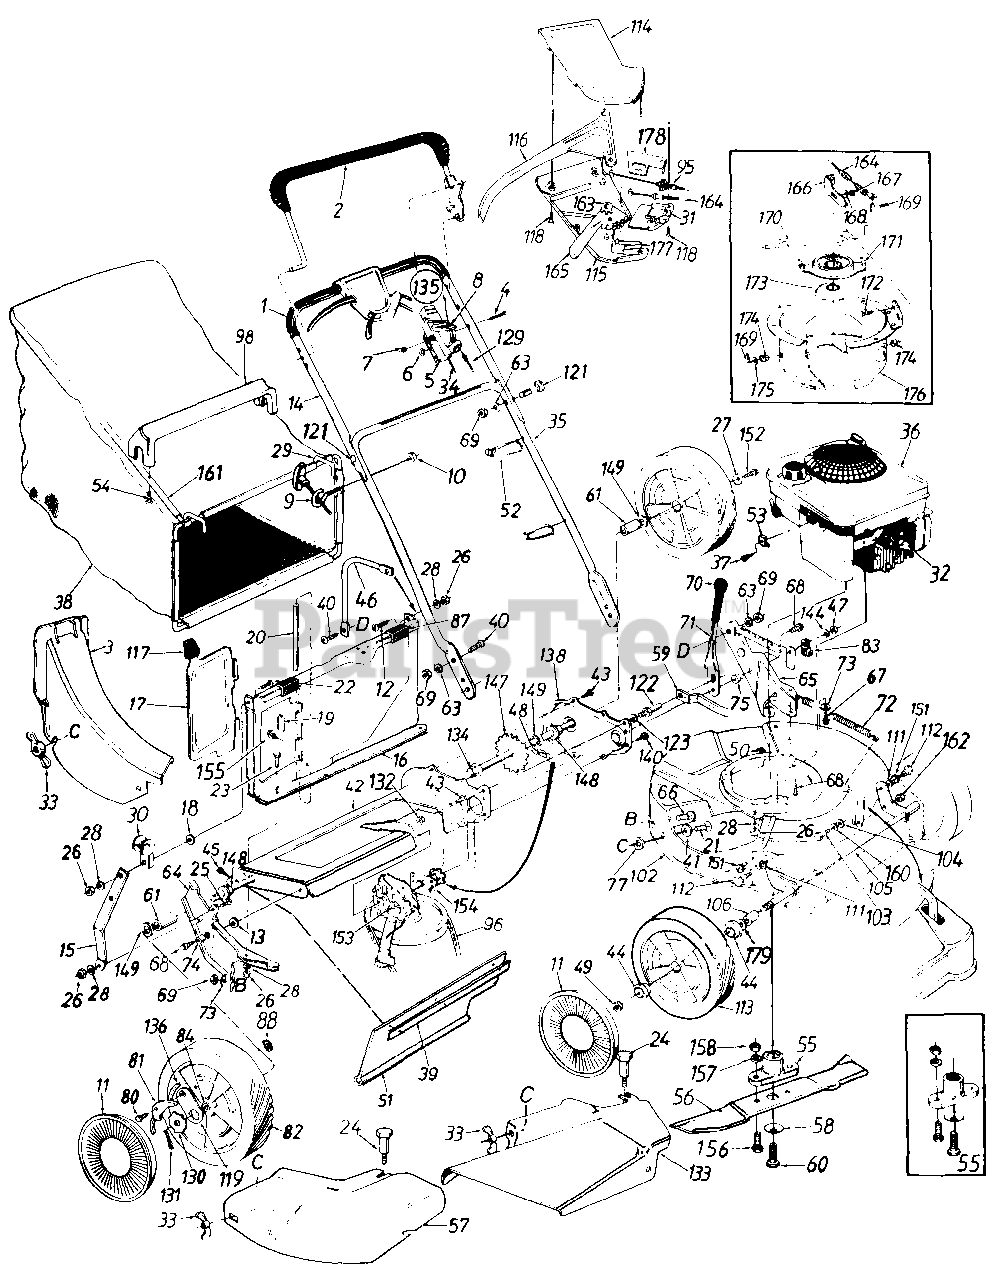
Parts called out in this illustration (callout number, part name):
1	Foam Grip
2	Control Handle Ass'y.
3	Rear Discharge Chute Ass'y.
4	Oval C-Sunk Scr.
5	Throttle Body
6	Spr. Wash. .66" I.D.
7	Hex L-Nut 1/4-20 Thd.
8	Throttle Lever
9	Rope Guide Bolt
10	Hex L-Nut 1/4-20 Thd.
11	Hub Cap
12	Truss Mach. Scr. 1/4-20 x .62" Lg.
13	Fl-Wash. .383" I.D. x 1" O.D.
19	Torsion Spring
21	Carriage Bolt 1/4-20 x .62"
22	Truss Mach. Scr. 1/4-20 x 3/4" Lg.
23	Hex Bolt 1/4-20 x .50" Lg.
24	Shoulder Bolt .312 Dia. x .18 Lg. - Special
25	Hex Bolt 1/4-20 x .62" Lg.
26	Hex Nut 1/4-20 Thd.
27	Bell-Wash. 1/4" I.D.
28	L-Wash. 1/4" I.D.
31	S.P. Control Cover
32	Spark Plug Insulator
33	Wing Nut w/Washer
34	Throttle Control Wire 61"
35	Lower Handle - Painted
36	Engine
37	Hex Self-Tap Scr. #10-32 x .62" Lg.
38	Grass Bag
39	Retaining Strip
40	Truss Mach. Scr. 5/16-18 x .75" Lg.
41	Fl-Wash. .344" I.D. x .62"
44	Flange Ball Bearing 1/2" I.D.
45	Hex AB-Tap Scr. 1/4 x .62"
46	Catcher Panel Support Arm
47	Hex Patch L-Nut 3/8-24 Thd.
48	#48 Chain .500" Pitch x 30 Links
49	Hex L-Nut 3/8-16 Thd.
51	Rear Flap 3.75" x 17.30" Lg.
52	Cable Tie
53	Cable Clamp
54	Hex AB Scr. #12 x 1.25" Lg.
55	Blade Adapter Kit
56	21" Blade
57	Mulching Plug
58	Bell-Wash. .46" I.D.
59	Height Adj. Connecting Arm
60	Hex Bolt 7/16-20 x 1.5" Lg. (Grade 5)
61	Spacer .513" I D. x .703" O.D. x .69" Lg.
63	L-Wash. 5/16" I.D.
64	R.H. Handle Wheel Brkt. Ass'y.
65	L.H. Handle Wheel Brkt. Ass'y.
66	Carriage Bolt 5/16-18 x .62"
67	Hex Wash. Hd. B-Tap Scr. 5/16-18
68	Hex Wash. Hd. TT-Tap Scr. 3/8-16
69	Hex Nut 5/16-18 Thd.
71	Height Adj. Lever
72	Extension Spring .75" O.D. x 8" Lg.
73	Bell-Wash. 5/16" I.D.
74	Spacer
75	Shld. Spacer .500" Dia.
77	Bolt Retainer 1/4 x .50" O.D.
80	Shld. Scr. .342" Dia. x .268
81	Pawl
82	Wheel Ass'y. Comp.
84	Bearing 1/2" I.D.
88	Weld L-Nut 1/4-20 Thd.
95	S.P. Cable
96	"V"-Belt
102	21" Deck Ass'y.
103	Shld. Bolt .5" Dia. x .295
104	Bell-Wash. .515" I.D. x 1.0" O.D.
105	Front Axle Ass'y.
106	Sleeve .526" I.D. x .690" O.D. x .880" Lg.
111	Intern. L-Wash. 3/8 I.D.
112	Shld. Bolt .575" Dia. x .42
113	Wheel Ass'y. Comp.
114	Self-Propelled Control Cover
115	Self-Propelled Control Cover
116	Control Lever
117	Door Grip
118	Fl-"C"-Sunk Hd. Tap Scr. #10 x .75" Lg.
119	Pawl Plate
121	Curved Carr. Bolt 5/16-18 x 1.38" Lg.
122	Shld. Pin 3/8-24 x 1.43" Lg.
123	L-Wash. 3/8" I.D.
129	Control Cable 47" Lg.
130	Ratchet Wheel 1.62" O.D.
131	Cotter Pin 1/8" Dia. x 1.00" Lg.
132	Hex Jam Nut 3/8-24 Thd.
133	Side Chute Deflector Ass'y.
134	Hex Flange Bearing
135	Throttle Box Comp.
136	Spring - Nylon
144	Fl-Wash. .385" I.D. x .87"
147	Rear Shaft Ass'y. 21.94" Lg.
148	Hex Flange Bearing .506" I.D. Plastic
149	Fl-Wash. .531" I.D. x .930"
151	Flanged Nyliner Brg.
152	Hex Bolt 1/4-20 x .62" Lg. (Grade 5)
153	Transmission Comp.
154	Hex Bearing Cup
155	Hex B-Tap Scr. #10 x .38
156	Hex Scr. 3/8-24 x 1.0" Lg.
157	L-Wash. 3/8" I.D.
158	Hex Nut 3/8-24 Thd.
160	Fl-Wash. .51" I.D. x .75" O.D.
162	Hex Jam Nut 3/8-16 Thd.
163	3 Tooth Rack Gear Insert
164	Spd. Control Cable - 50" Lg.
165	6-Spd. Shift Lever
168	Hex Cent. L-Nut 1/4-20 Thd.
169	Cot-Pin 3/32" Dia. x .75" Lg.
171	Movable Pulley Half Ass'y.
172	Carr. Bolt 1/4-20 x .50" Lg.
173	Spined Pulley Half
174	Flanged Bushing
175	Fl-Wash. .328" I.D. x .68" O.D.
176	Cable Mtg. Brkt. Ass'y.
177	Shift Lever Spring
178	6-Speed Rack Cable Brkt.
179	Fl-Wash. .385" I.D.
